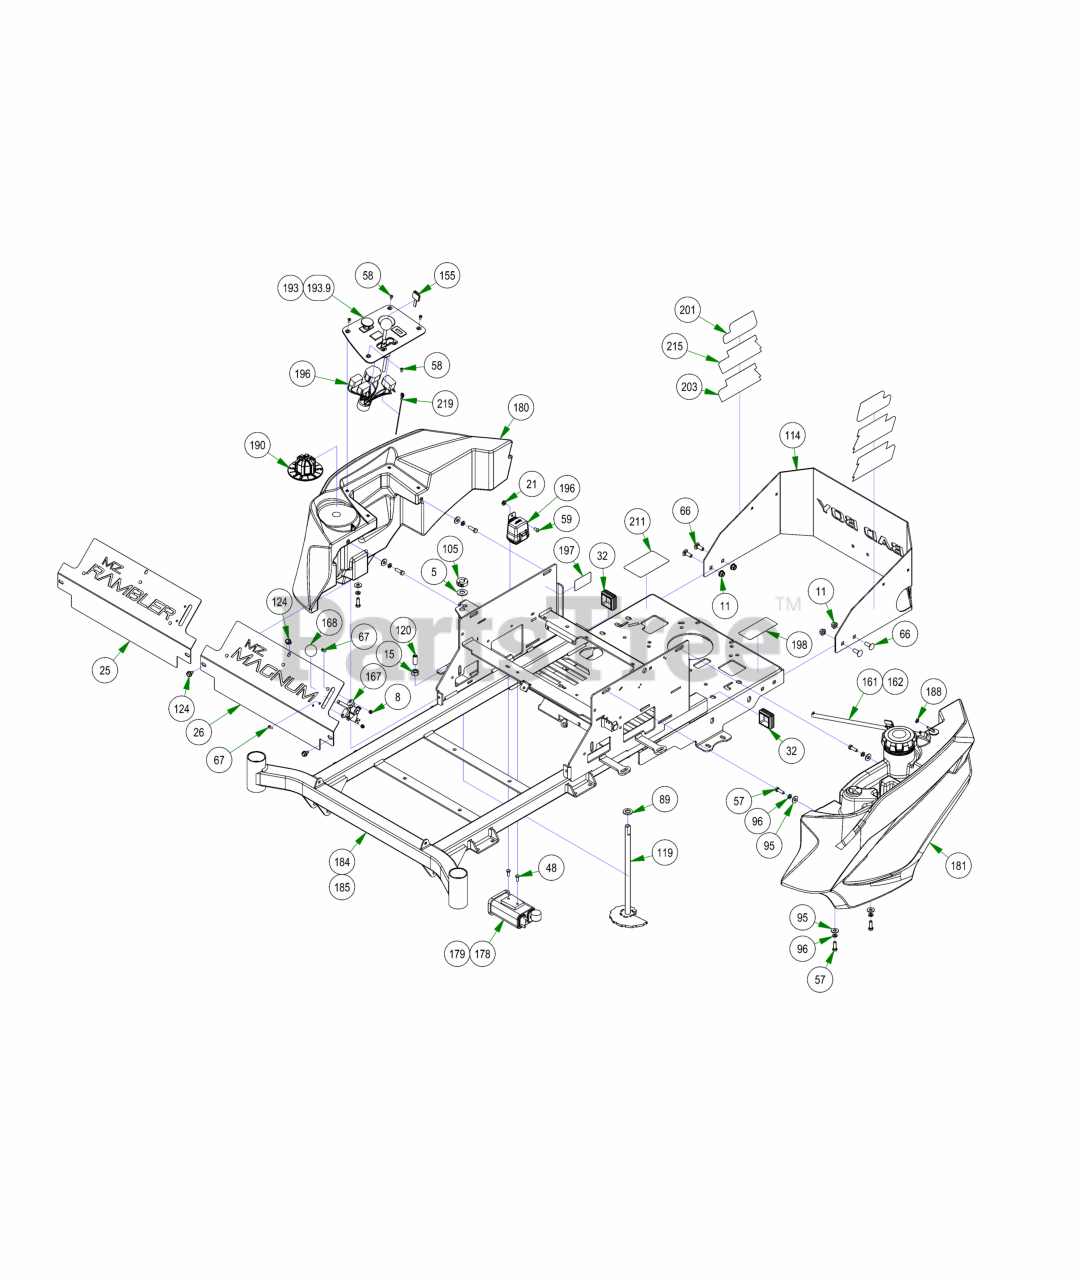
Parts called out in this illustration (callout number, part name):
5	.625 ID x 1.250 OD x .062 THK F/W Nylon
8	10-24 NYLON INSERT LOCKNUT ZINC
11	3/8-16 NYLON INSERT FLANGE LOCKNUT (GR.F) ZINC
15	1/2-13 HEX NUT ZINC
21	1/4-20 HEX SERRATED FLANGE NUT HARD/ZINC
25	2023 MZ Rambler Cooler Cover Assembly
26	2023 MZ Magnum Cooler Cover Assembly
32	2X2 Frame Plug
48	M6-1.0 X 16MM DIN 933 HEX TAP BOLT (CL 8.8) ZINC
57	5/16-18 X 1 HEX CAP SCREW (GR.5) ZINC
58	10-32 X 3/8 BUTTON SOCKET CAP SCREW 18-8 STAINLESS STEEL
59	1/4-20 X 1/2 BUTTON SOCKET CAP SCREW 18-8 STAINLESS STEEL
66	3/8-16 X 1 CARRIAGE BOLT (GR.5) ZINC
67	10-24 X 5/8 BUTTON SOCKET CAP SCREW 18-8 STAINLESS STEEL
89	.635 ID X 1.120 OD X .140 THICK FLAT WASHER NYLON
95	5/16 USS FLAT WASHER (7/8 OD) ZINC
96	5/16 SPLIT LOCKWASHER ZINC
105	5/8" Split Collar
114	2022 MZ Rear Plate
119	Deck Height Dial Rod Assembly
120	Dial Rod Plunger
124	5/16-18 X 1/2 HWH unslot (F) tcs zinc
155	Ignition Key
162	37" Fuel Line Assembly
162.3	2 Way Fuel Shut-Off Valve
162.4	Fuel Line 4" Section with Clamps
162.4.1	1/4 Fuel Hose Clamp
162.4.2	4" 1/4 Fuel Line
167	Universal Throttle Head - 2012
168	Throttle Knob
178	MZ Kohler 42" EPA Canister Assembly
179	MZ Kohler EPA Canister Assembly
180	2017 MZ Right Console
181	2017 MZ Left Gas Tank
184	2023 MZ 42-48 Frame - Painted
185	2023 MZ-Avenger 54-60 Frame - Painted
188	3/16 Vinyl Clamp
190	MZ/ZT Deck Height Dial
192	2023 Rambler Control Panel Assembly
193	2023 Control Panel Assembly
196	Wiring Harness
197	ANSI Decal BMZ54KT740
198	2023 EPA Build Date Punch Decal
201	540CC Back Plate Cluster
203	2018 Magnum 725cc Back Plate Cluster
211	Pump Belt Route Decal-Pump Plate
215	724cc Back Plate Cluster
219	2017 MZ/ZT/MAV Tach Wire Assy
